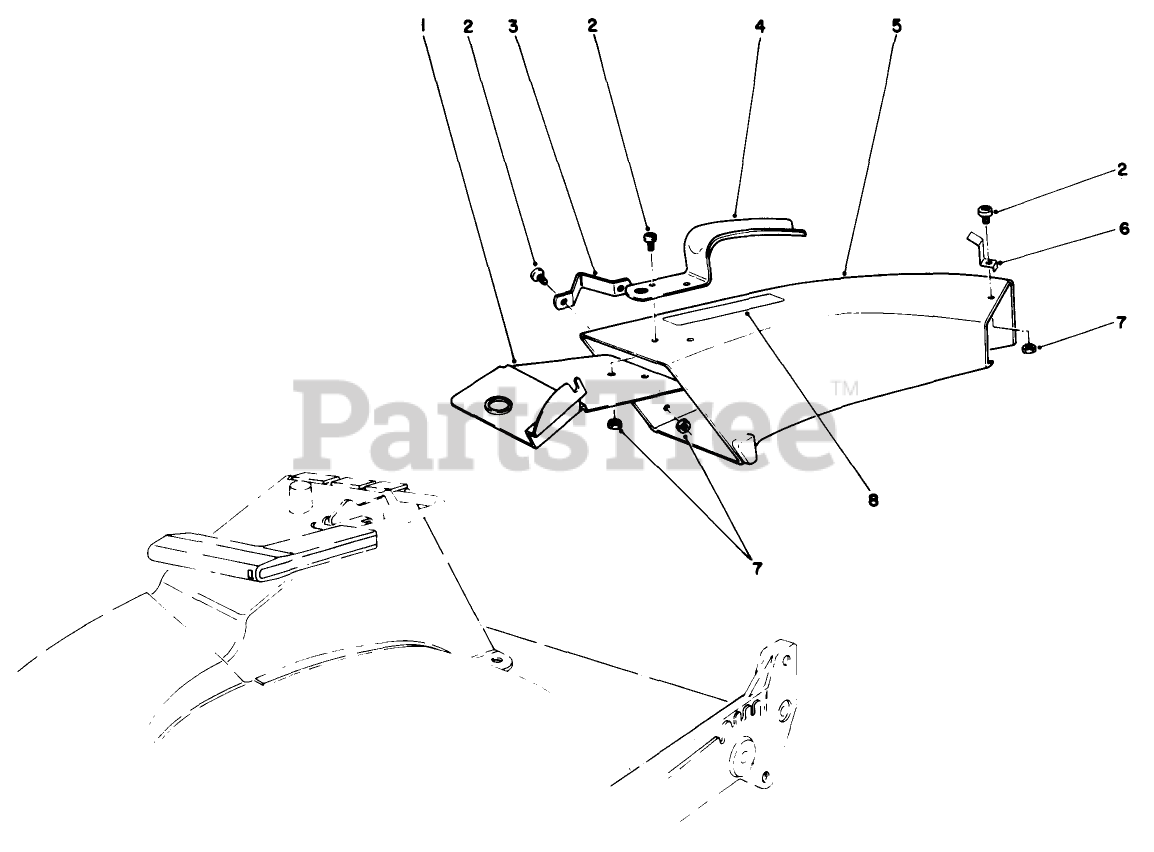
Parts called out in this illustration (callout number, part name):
2	10-24 X 5/8 PAN HD MS
4	CHUTE HANDLE
5	Chute-Discharge
7	NUT-LOCK, NI
